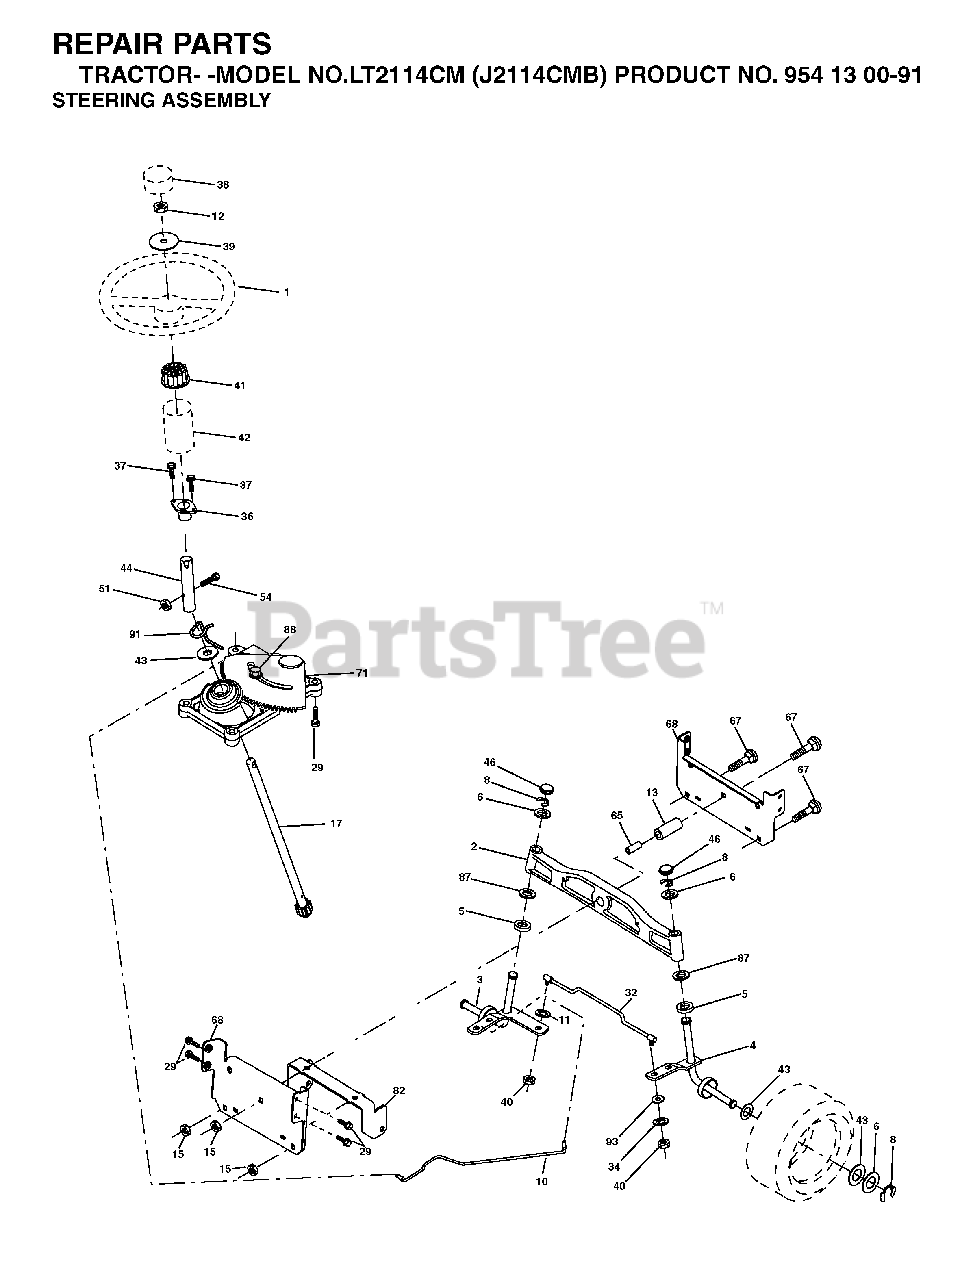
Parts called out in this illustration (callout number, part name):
2	AXLE ASSY FRONT
3	SPINDLE.ASM.LH.15"TIRES
4	SPINDLE.ASM.RH.15"TIRES
8	RING CLIP
10	DRAGLINK.15".TIRES.2001
11	WASHER, LOCK 3/8
12	NUT.HEX.1/2-20
13	TUBE, PIVOT AXLE
15	NUT
17	SHAFT ASM, STEERING
29	SCREW 3/8-16X3/4
32	ROD.ASM.TIE.BALL.JOINT.NOVAN
33	WASHER M
34	LOCKWASHER
35	NUT, CROWNLOCK
36	BUSHING, STEERING
40	GRIPCO NUT
41	STEERING WHEEL ADAPTOR
42	BOOT.STEERING.SHAFT.BLACK
44	EXT, STEERING SHAFT
46	CAP.SPINDLE
51	CROWN LOCKNUT
65	SPACER BRACE AXLE
67	BOLT
68	BRACE.AXLE.15"TIRES
71	STEERING ASM
82	BRACKET
87	WASHER, FLAT .781 X 1 1/2"
88	BOLT, SHOULDER 7/16-20
91	CLIP.STEERING
